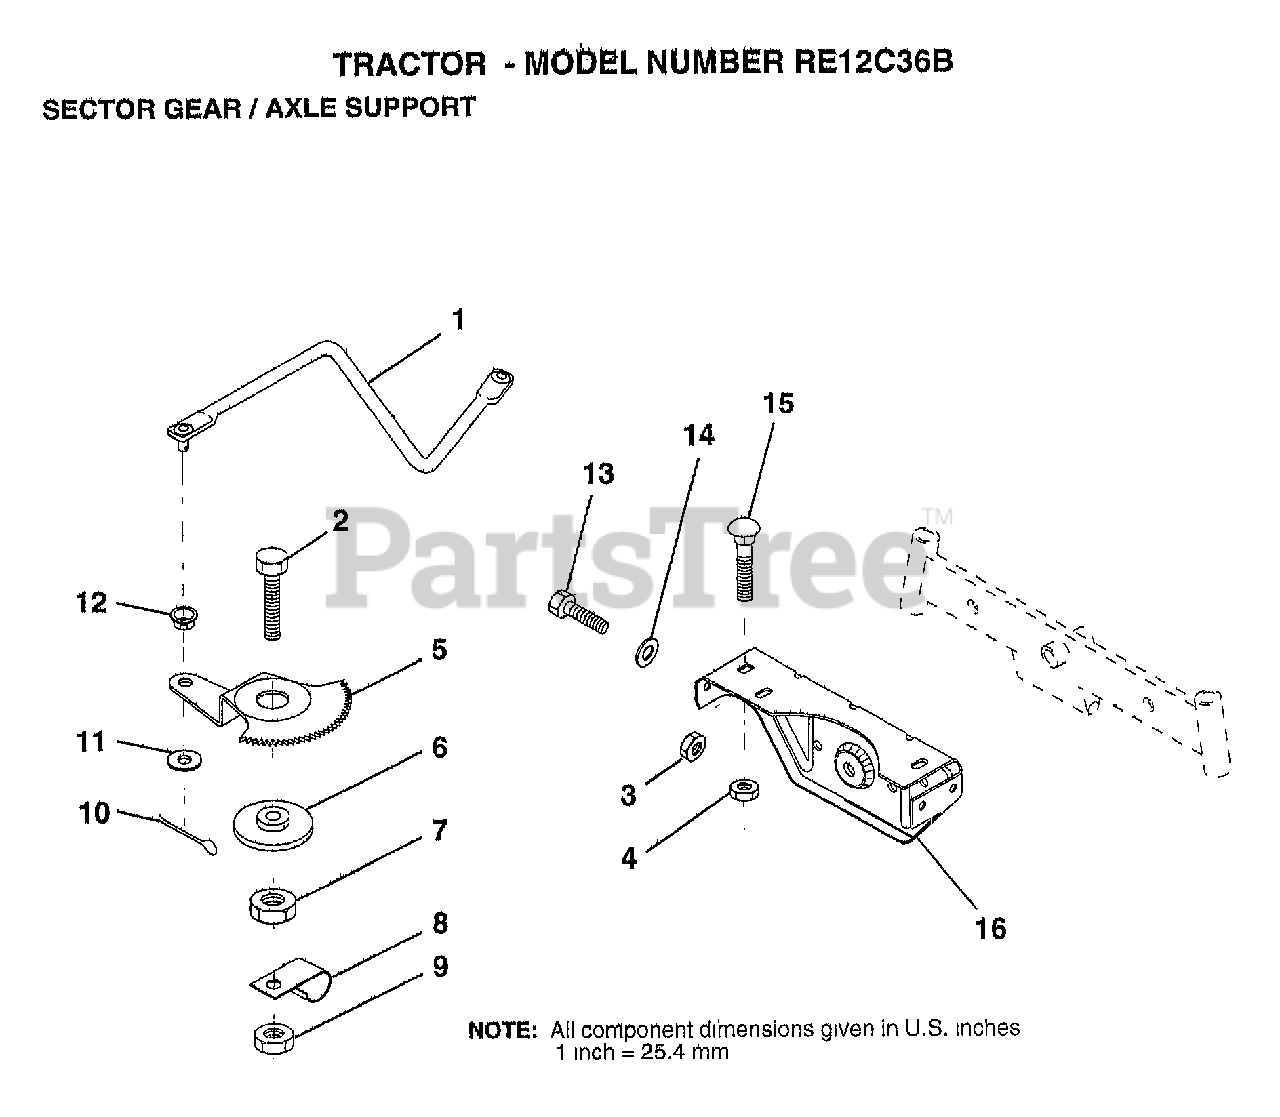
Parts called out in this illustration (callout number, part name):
1	DRAG LINK
2	"BOLT,HEX"
5	GEAR SECTOR
6	BUSHING
7	NUT
8	CLIP INSULATOR
9	NUT LTV
10	COTTER PIN
11	WASHER
12	BUSHING.DRAGLINK
13	BOLT
14	WASHER
15	BOLT
16	SUPT AXLE FRONT
